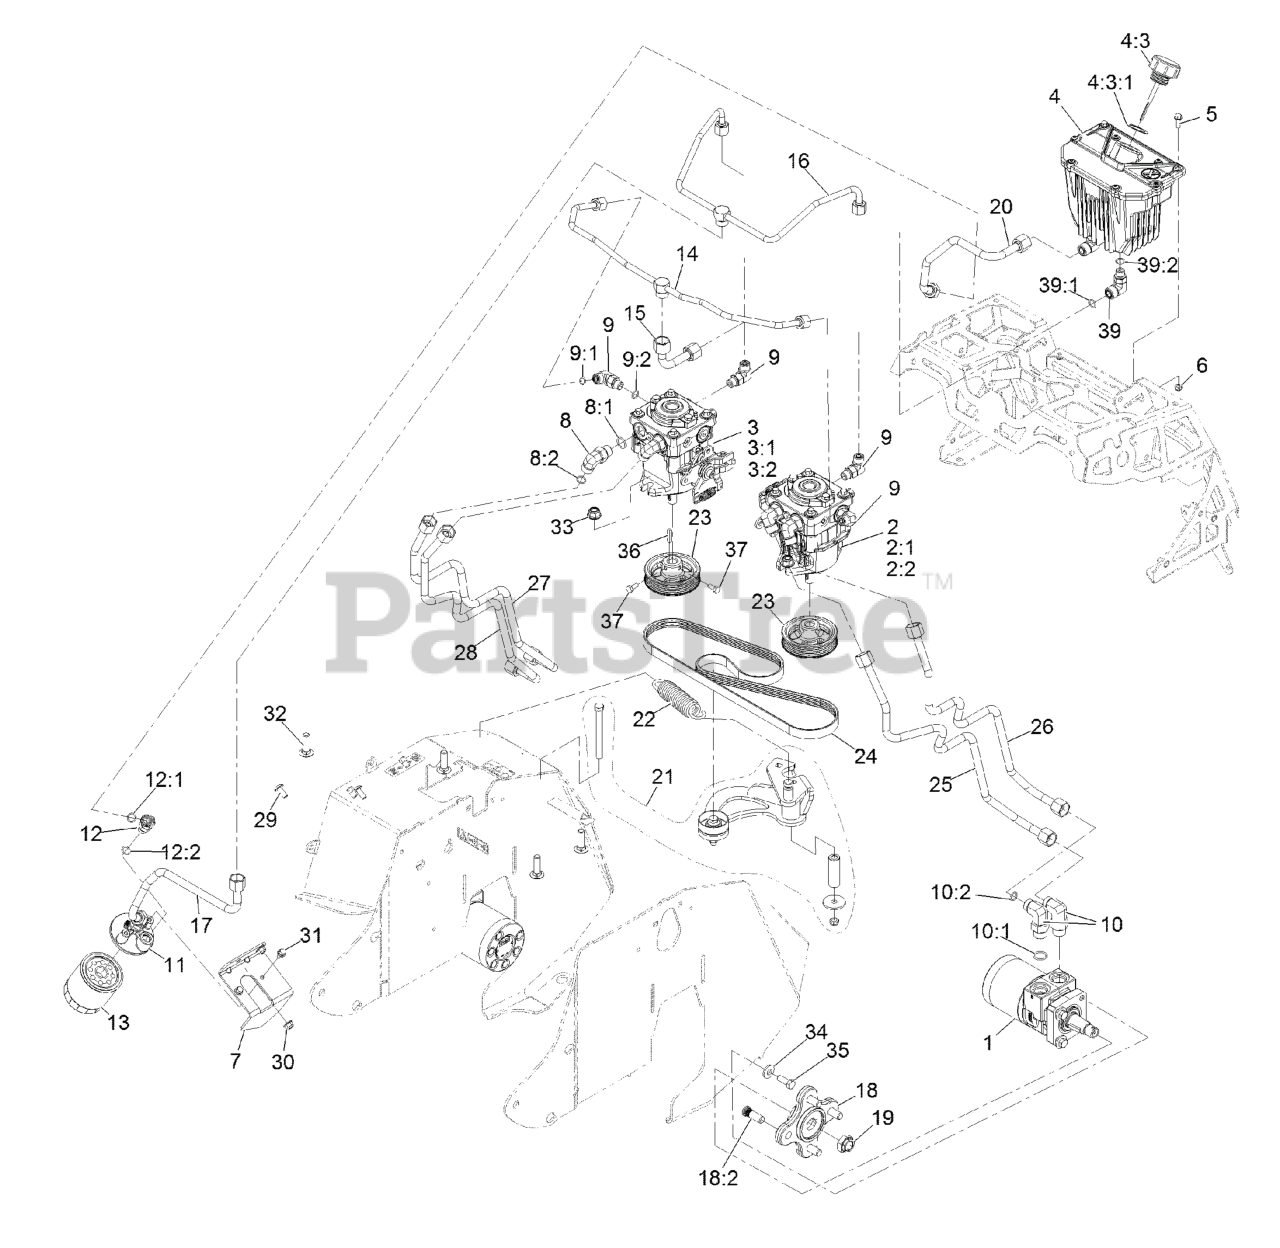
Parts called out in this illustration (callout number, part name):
1	MOTOR-WHEEL
2	PUMP-HYDRAULIC 10CC
2:1	KIT, 10CC/12CC PUMP KIT
2:2	SEAL OVERHAUL KIT
3	PUMP-HYDRAULIC 10CC
3:1	KIT, 10CC/12CC PUMP KIT
3:2	SEAL OVERHAUL KIT
4	ASM, HYDRAULIC RESERVOIR
4:3	RESERVOIR CAP ASM
4:3:1	GASKET-CAP
5	SCREW-HWH
6	NUT-LOCK, NI
7	BRACKET-FILTER
8	FITTING-ELBOW, 90 DEG
8:1	O-RING
8:2	O-RING
9	FITTING-ELBOW, 90 DEG
9:1	O-RING
9:2	O-RING
10	FITTING-ELBOW, 90 DEG
10:1	O-RING
10:2	O-RING
11	HEAD-FILTER
12	Adapter
12:1	O-RING
12:2	O-RING
13	FILTER-25 MICRON, BI-DIRECTIONAL
14	LINE, HYDRAULIC, CASE TEE
15	LINE, HYDRAULIC, CASE
16	LINE, HYDRAULIC, CHARGE TEE
17	LINE-HYDRAULIC CHARGE
18	ASM-HUB AND STUDS
18:2	STUD-WHEEL
19	NUT-LOCK
20	LINE-HYDRAULIC SUPPLY
21	ASM, IDLER ARM
22	SPRING, EXTENSION
24	BELT, PVK5
29	SCREW-TORX
30	NUT-HF, NI
31	SCREW-HHF
32	BOLT-CARR
33	NUT-HF, NI
34	WASHER-BELLEVILLE
35	SCREW-HH
36	KEY, 5MM X 5MM X 29MM
37	Screw-SQH
39	Fitting-HYD, 90 DEG
39:1	O-RING
39:2	O-RING
40	Washer-Thrust
